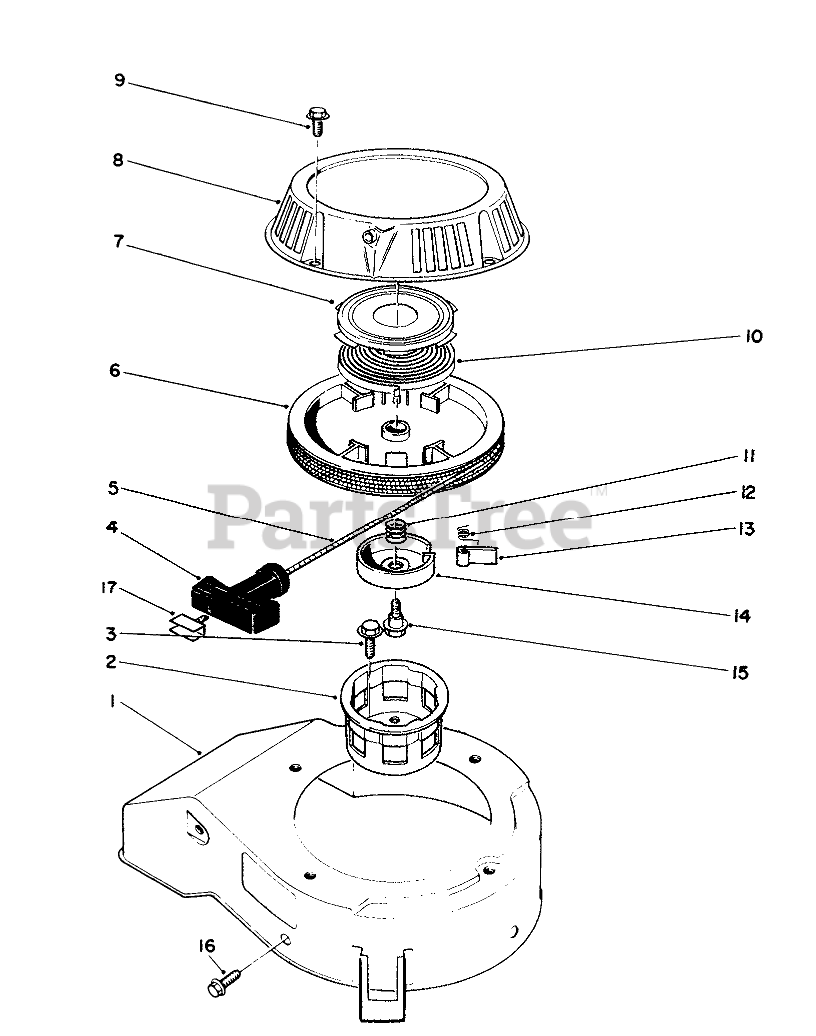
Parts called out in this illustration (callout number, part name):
1	COVER
2	CUP - STARTER
4	HANDLE-RECOIL
5	ROPE-STARTER
7	Retainer-Recoil Spring
9	SCREW-HHF
10	Spring-Recoil
11	SPRING
12	SPRING
14	RETAINER
17	Insert Handle
